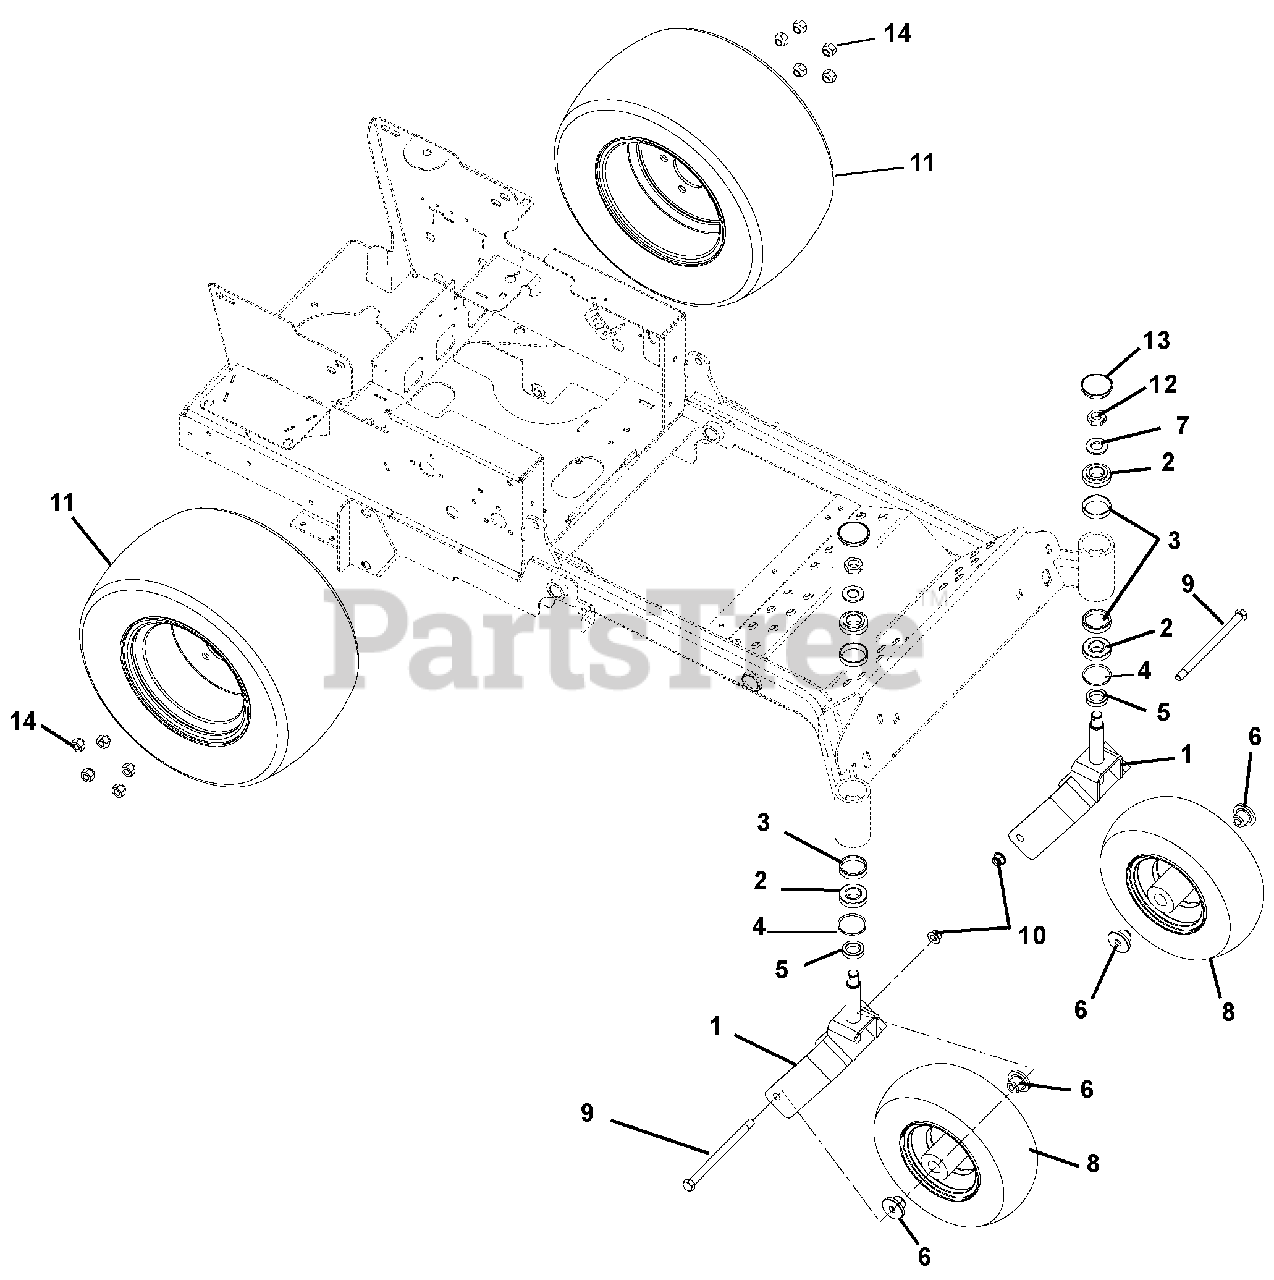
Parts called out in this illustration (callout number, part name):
1	WLDMT, FORK
2	BRG, CONE W/ GREASE
3	BRG-CUP1.980X.420
4	BEARING SEAL 1.5 X 2 X .18
5	SPACER 1.005X1.5075X.375
6	SPACER, FRONT WHEEL
7	@WSHR-FL-STL.812X1.50X.135YWZC
8	TIRE/WHEEL ASSY, 13X5.00-6
9	@BLT-HEX .50-13X7.50 GR5 YWZC
10	@NUT-LK-NYL-FLG .50-13 YWZC
11	TIRE/WHEEL ASSY, 20X10-8
11	TIRE, 20X10.00-8
11	TIRE/WHEEL ASSY, 20X10.00-10
11	TIRE, 20X10.00-10
12	NUT-JAM CTRLK .75-16 YWZC
13	CAP, DUST
14	WHEEL NUT .500-20 YZ
15	BRG, 25MM ID X 52MM OD X 15MM
